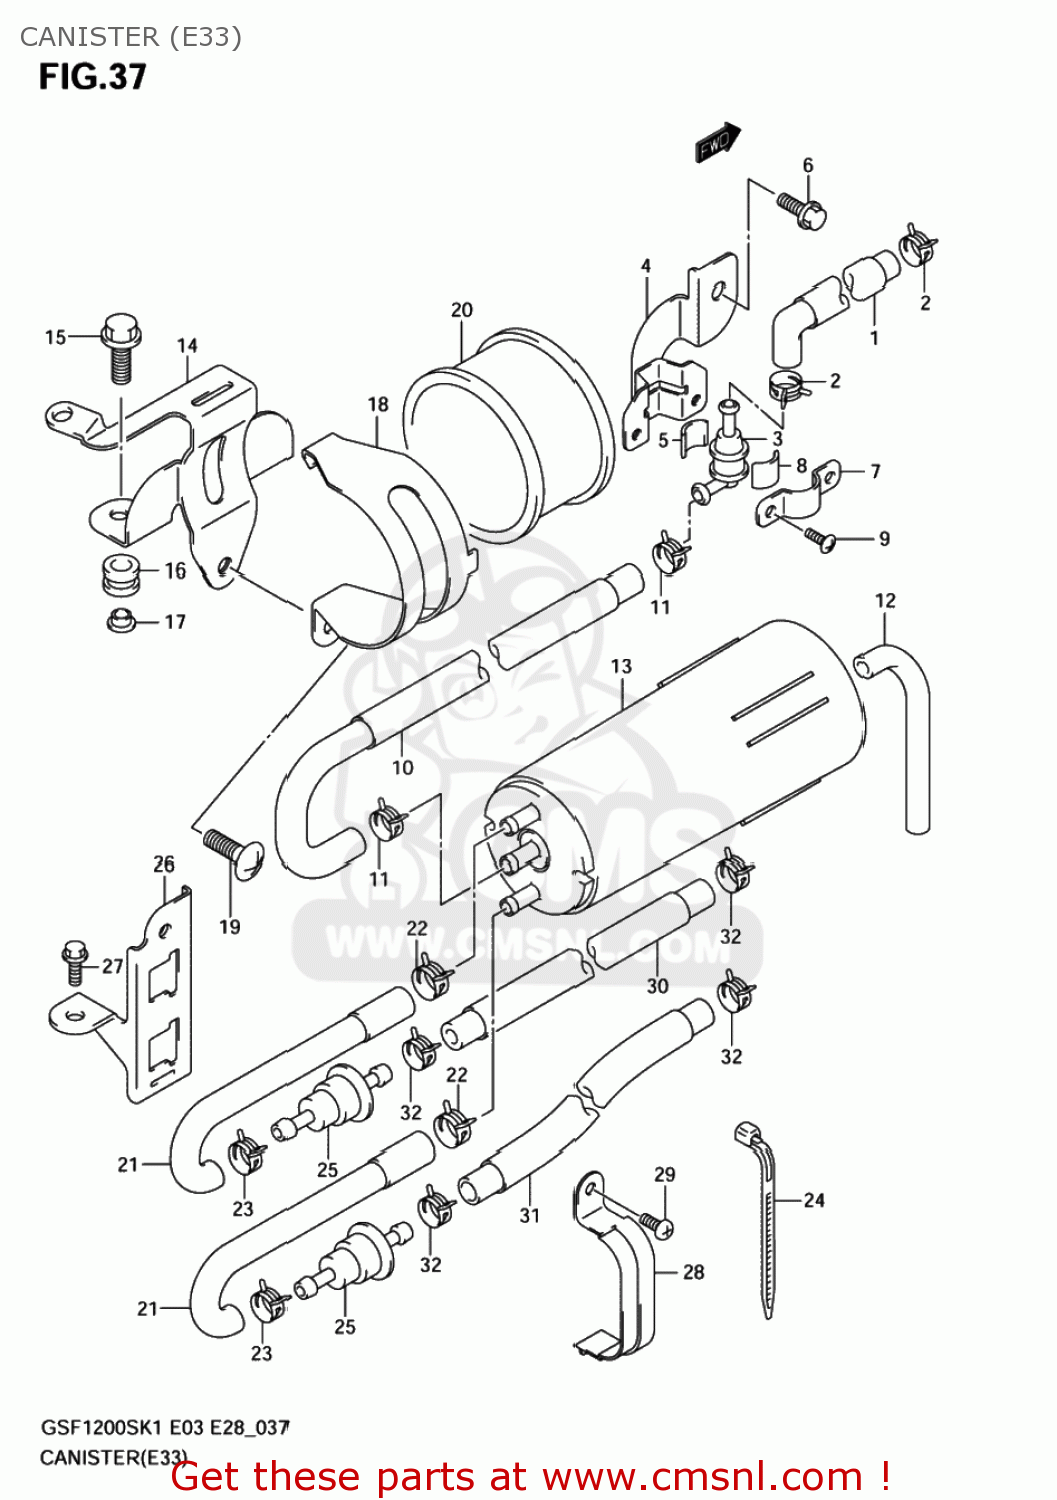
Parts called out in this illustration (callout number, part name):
1	HOSE TANK & BREATHER VALVE
2	CLIP
3	VALVE,FUEL TANK BREATHER
4	BRACKET,FUEL TANK BREATHER
5	CUSHION
6	BOLT
7	PLATE,FUEL TANK BREATHER NO.2
8	CUSHION
9	SCREW
10	HOSE,CSTR & BREATHER VALVE
11	CLIP
12	HOSE,DRAIN
13	CANISTER ASSY,CHARCOAL
14	BRACKET,CANISTER
15	BOLT(6X25)
16	CUSHION
17	WASHER
18	HOLDER,CANISTER
19	SCREW 6X12
20	CUSHION,CANISTER
21	HOSE,CSTR & PURGE VALVE
22	CLIP
23	CLIP
24	CLAMP(L:165)
25	VALVE,CANISTER PURGE
26	BRACKET,CANISTER PURGE VALVE
27	BOLT
28	HOLDER,CANISTER PURGE
29	SCREW
30	HOSE,CARB & PURGE VALVE
31	HOSE,CARBURETOR & PURGE VALVE
32	CLIP
